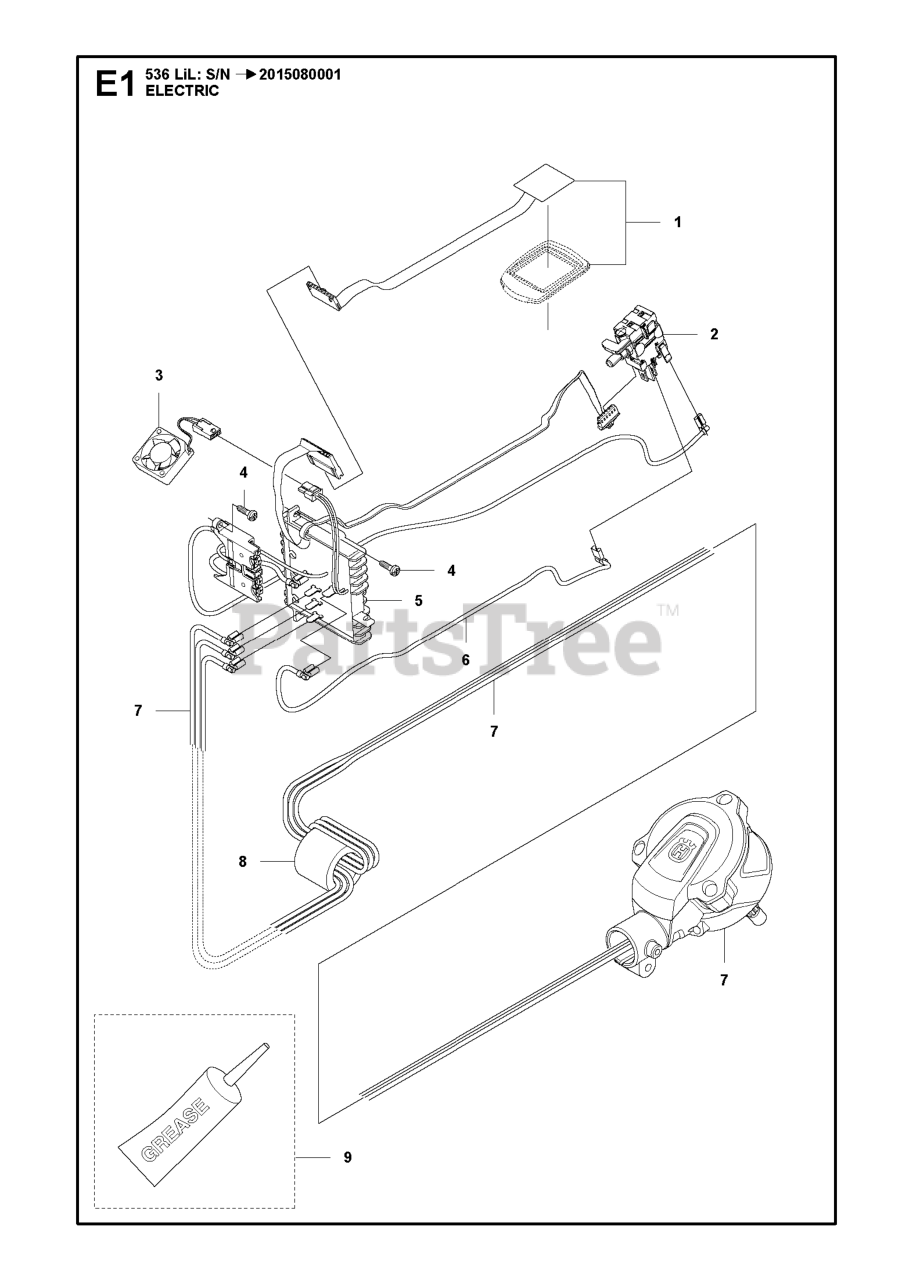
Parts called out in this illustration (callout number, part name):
2	TRIGGER SWITCH
5	CONTROL UNIT
6	WIRING ASSY
8	FERRITE CORE
9	GREASE TUBE Q8 RUYSDAEL WR2
